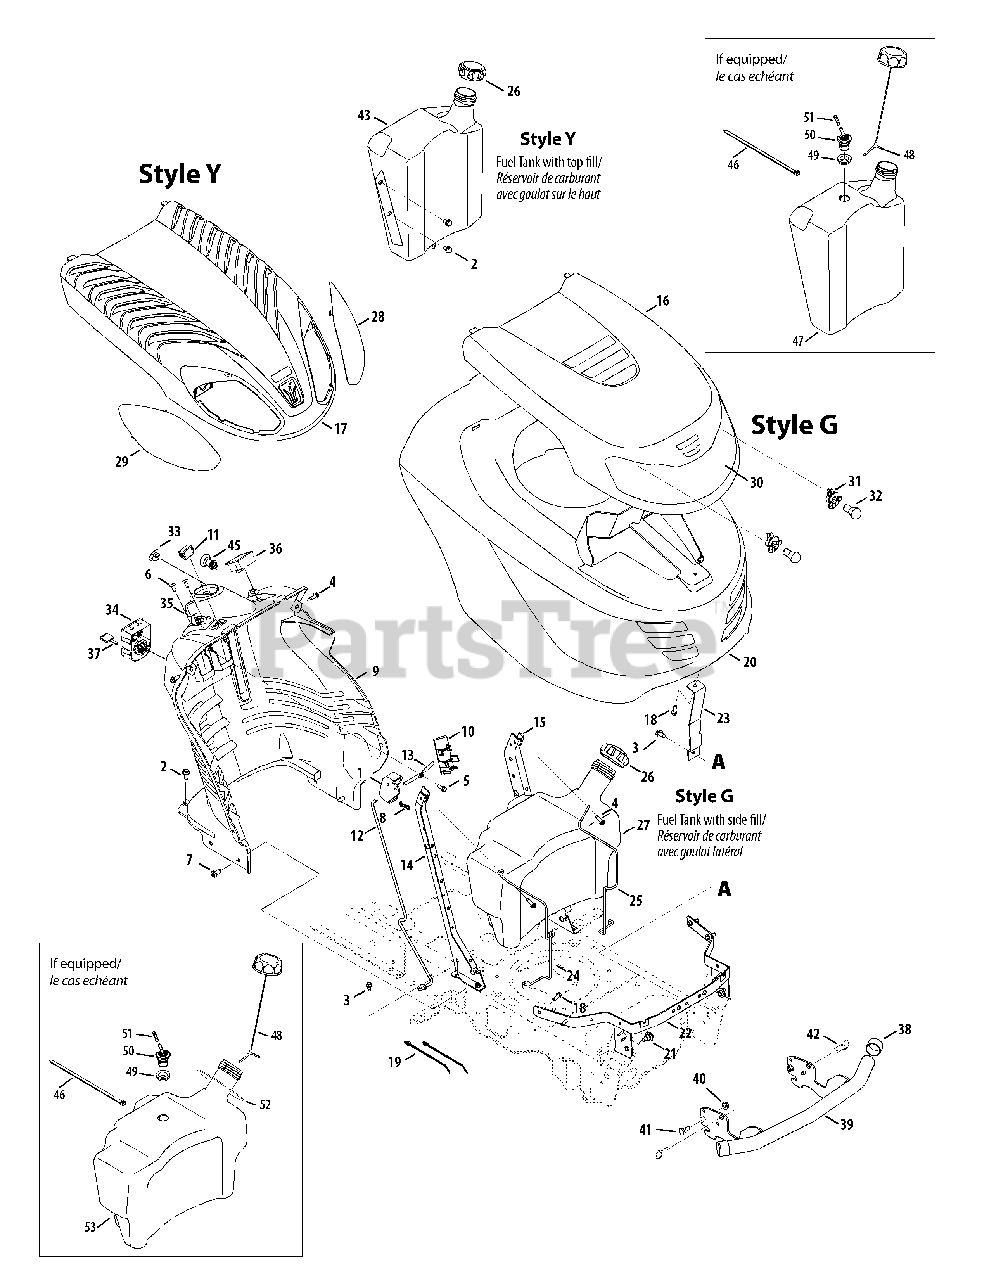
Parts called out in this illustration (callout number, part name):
2	S-Tapp Scr 5/16-18 x .75
3	Hex Wash S-Tapp Scr 1/4-20 x .50
4	Hex TT Screw 1/4-20 x .75
5	Hex Tapp Scr 1/4 x .75" Lg.
6	Torx Mach. AB-Tapp Scr. 1/4-14 x .625 Lg
7	Screw 5/16-18 x .75
8	Bow-Tie Cotter Pin
9	Dash Panel (Man. PTO w/fuel level window)
9	Dash Panel (Elect. PTO w/o fuel level window)
10	Cruise Cover Y/G Style
11	Light Switch Cap
12	Latch Control Rod
14	RH Dash Support Plate
16	Up per "G" Style Hood
17	Up per "Y" Style Hood
18	Screw, Bos, 1/4 Dia. x .75
20	G Style Hood (w/side fill fuel tank)
20	Y Style Hood (w/top fill fuel tank)
21	Shoulder Screw .43 x .29, 5/16-18
23	Hood Support Bracket
24	Tank Support Rod RH
25	Tank Support Rod LH
26	Cap-Fuel
27	Fuel Tank 2.75 Gal. (side fill)
28	Lens LH - Style "Y"
29	Lens RH - Style "Y"
29	Lens (Style G)
29	Reflector Label
31	Socket
32	Miniature Lamp 12V Socket Type
34	Key Switch Module
35	Throttle/Choke Cont. Cable 25" Lg. (Single)
35	Throttle/Choke Cont. Cable 46.5" Lg.(Twin)
36	Ammeter
37	Ignition Key w/Plastic Cover
40	Hex Lock-Nut 3/8-16 Gr.B
41	Shoulder Scr. .498 x .340: 3/8-16
42	Quick Pin 1/2" dia. x 0.50
43	Fuel Tank 2.0 Gal. (top fill)
43	Fuel Tank 3.0 Gal. (top fill)
45	Electric PTO Switch
47	Tank Ass'y 1.36 Gal.
48	Cap-Fuel
49	Rubber Grommet
50	Roll over Valve
53	Fuel Tank 2.06 Gal. (side fill)
